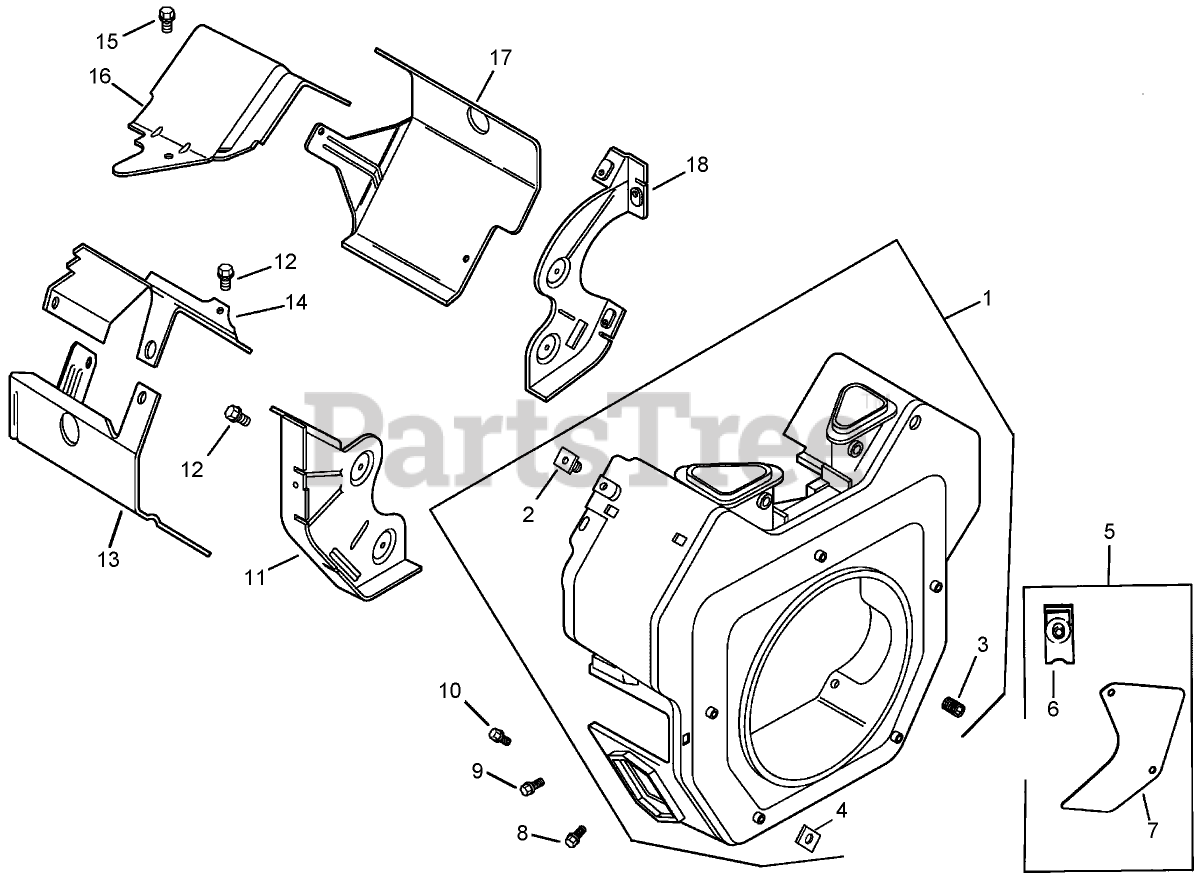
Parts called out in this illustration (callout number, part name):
1	Blower Housing ASM (Includes 2-5)
2	NUT-PLASTIC
3	Screw-Set (10-24X.25)
4	Nut-Plastic
5	Access Cover Kit (Includes 6, 7)
6	Clip-Mounting
7	Panel-Access
8	Screw-Hex Flange, Heavy (M5x0.8x16)
9	SCREW-FLANGE, THREAD FORMING (M5X0.8X16)
10	SCREW-FLANGE, THREAD FORMING (M5X.8X20)
11	Plate-Backing (No. 2 Side)
12	SCREW-FLANGE, THREAD FORMING (M6X1.0X16)
13	Baffle-Barrel, Cylinder (No. 2 Side)
14	BAFFLE-VALLEY (No. 2 SIDE)
15	Screw-HF (M5x0.8x10)
16	BAFFLE-VALLEY (No. 1 SIDE)
17	Baffle-Barrel, Cylinder (No. 1 Side)
18	Plate-Backing (No. 1 Side)
